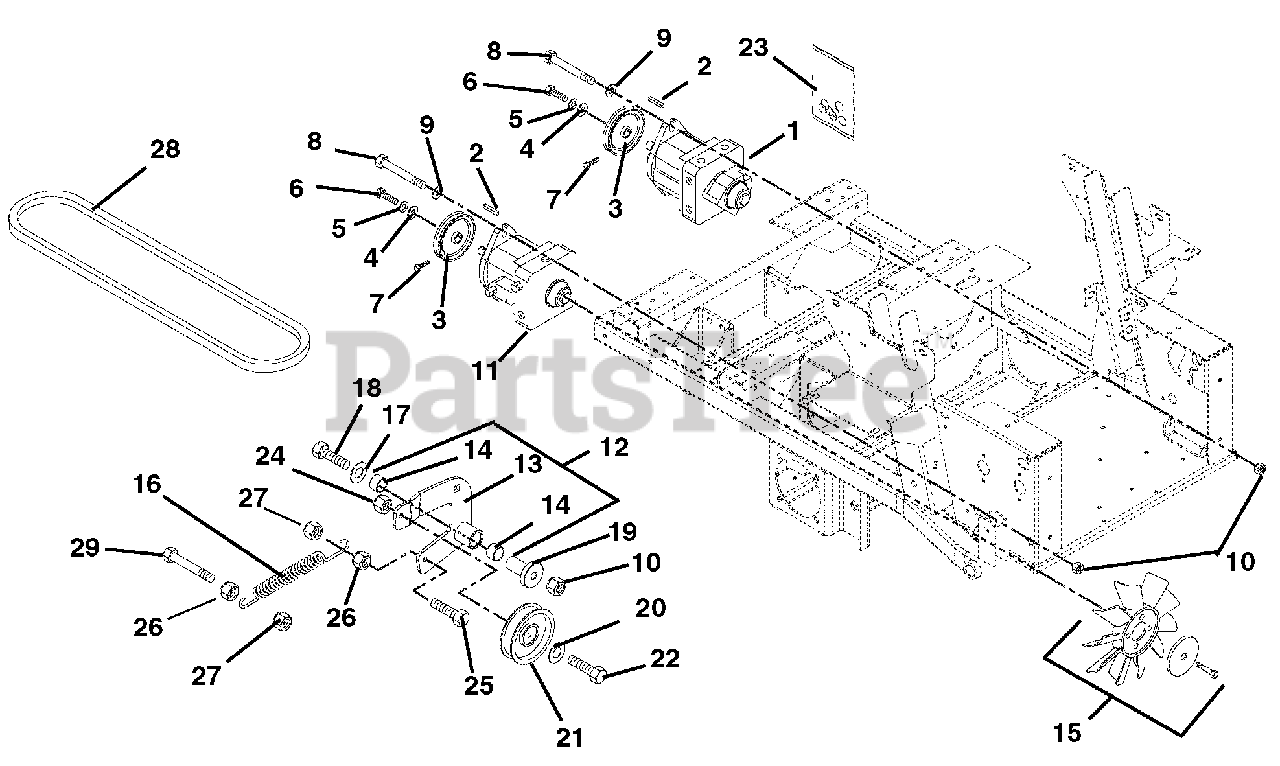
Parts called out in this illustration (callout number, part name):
1	Pump, Hydraulic (RTN) with Auxiliary
2	Key, Square 5 x 5 x 30mm Plain
3	Sheave, Poly-V .671 x 4.125
4	Washer, Flat Steel .25 x 1.0 x .048
5	Washer, Locking .25 x .062
6	Bolt, Hex M6 x 1.0 x 12
7	Screw, Socket Head .25-20 x .50
8	Bolt, Hex .50-13 x 1.50 Grade 5
9	Washer, Flat Steel .531 x 1.06 x .095
10	Nut, Locking Top Flange .50-13
11	Pump, Hydraulic (RTN)
12	Assembly, Idler Arm Guard Drive (Includes 13 & 14)
13	Weldment, Idler Arm Ground Drive
14	Bearing, 1.00 x 1.12 x .75
15	Fan, Hydro Pump Cooling
16	Spring, Tension .120 x .845 x 6.500
17	Washer, Flat Steel .39 x.75 x.125
18	Bolt, Hex .50-13 x 3.50 Grade 5
19	Bearing, Pedestal Powdered Metal
20	Washer, Flat Steel .406 x .812 x .065
21	Idler, Flat 4.00 x 1.06
22	Bolt, Hex .38-16 x 2.25 Grade 5
23	Kit, Pump Seal (One kit required for each pump)
24	Nut, Locking Top Flange .38-16
25	Bolt, Hex .31-18 x 1.25 Grade 5
26	Nut, Hex .31-18
27	Nut, Locking Top Flange .31-18
28	Belt, Poly-V 49.50
29	Bolt, Hex .31-18 x 2.50 Grade 5
